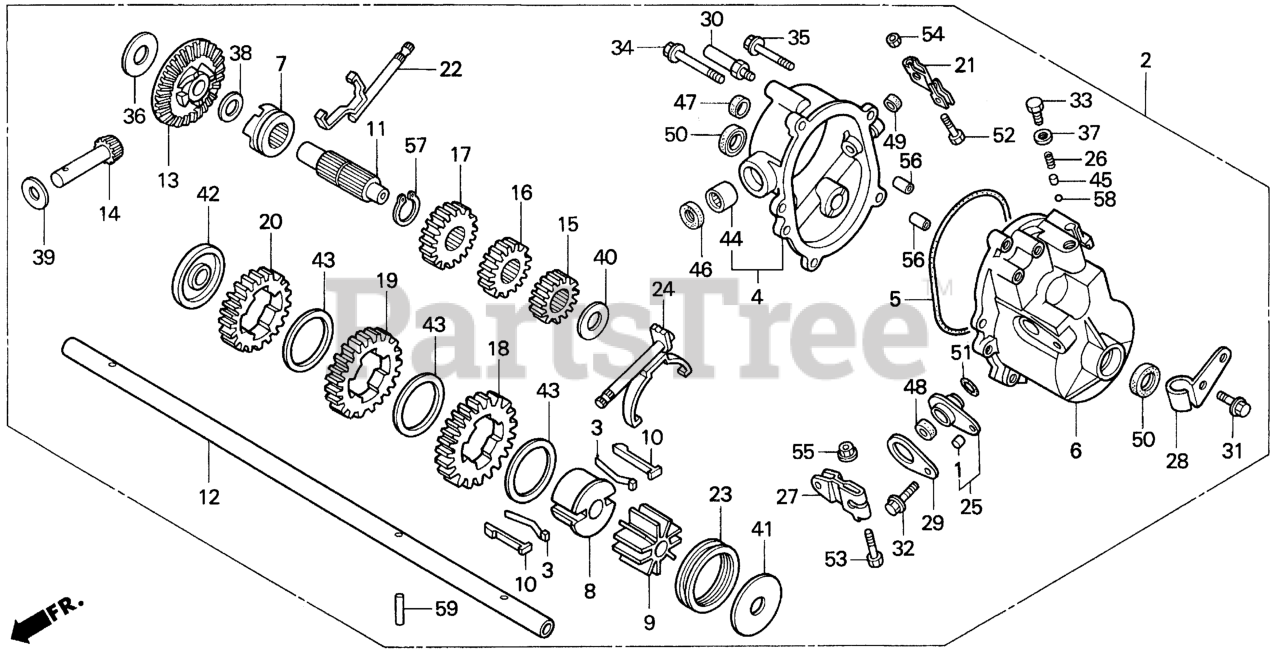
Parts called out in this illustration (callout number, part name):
1	COLLAR, FAN
2	TRANSMISSION ASSY.
3	SPRING, CHANGE KEY
4	CASE ASSY., R. TRANSMISSION
5	O-RING, TRANSMISSION CASE
6	CASE ASSY., L. TRANSMISSION
7	CLUTCH, DRIVEN
8	BOSS, CHANGE SHAFT
9	HOLDER, KEY
10	KEY, CHANGE SHAFT
11	COUNTERSHAFT
12	SHAFT, FINAL
13	GEAR, BEVEL (44T)
14	PINION, BEVEL
15	GEAR, FIRST DRIVE (14T)
16	GEAR, SECOND DRIVE (18T)
17	GEAR, THIRD DRIVE (20T)
18	GEAR, FIRST DRIVEN (33T)
19	GEAR, SECOND DRIVEN (29T)
20	GEAR, THIRD DRIVEN (27T)
21	ARM, CLUTCH
22	SHAFT, SHIFT
23	SHIFTER
24	FORK, SHIFT
25	GUIDE, CHANGE LEVER
26	SPRING, BALL SETTING
27	ARM, CHANGE
28	BRACKET, WIRE HOLDER
29	HOLDER, SHIFT SHAFT
30	BOLT, GUIDE
31	BOLT, FLANGE (6X12) (CT200)
32	BOLT, FLANGE (6X16)
33	BOLT, HEX. (8X10)
34	BOLT, FLANGE (6X25)
35	BOLT, FLANGE (6X25)
36	WASHER, THRUST (14X32X1)
37	WASHER, SEALING (8X16X1.6)
38	WASHER (14MM)
39	WASHER (10X21)
40	WASHER B, THRUST (12MM) (1.0)
41	WASHER, THRUST (15X45X1.5)
41	WASHER, THRUST (15X45)
42	WASHER, SPECIAL (15MM)
43	WASHER (35X45X1)
44	BEARING, NEEDLE (10X17X20)
45	RETAINER, BALL (6MM)
46	OIL SEAL (10X17X4) (ARAI)
46	OIL SEAL (10X17X4)
47	PLUG, SEALING (14X4)
48	OIL SEAL (8X16X6)
49	OIL SEAL (8X14X5)
50	OIL SEAL (15X24X5)
51	O-RING (12.3X1.9)
52	BOLT, HEX. (5X20)
53	BOLT, HEX. (6X25)
54	NUT, HEX. (5MM)
55	NUT, FLANGE (6MM)
56	PIN A, DOWEL (8X14)
57	CIRCLIP (OUTER) (18MM)
58	BALL, STEEL (#6) (3/16)
59	ROLLER (6X22.4)
